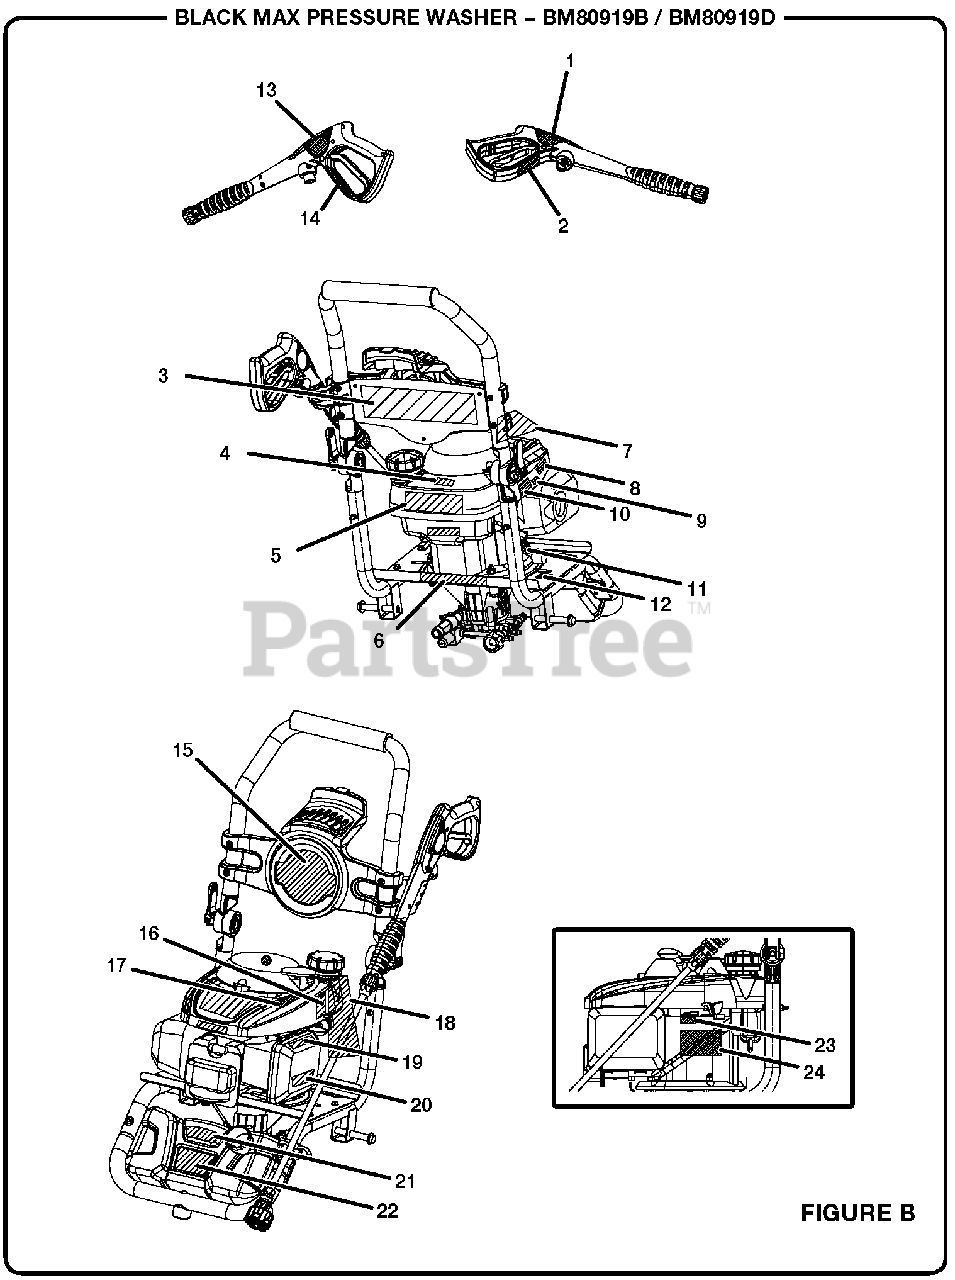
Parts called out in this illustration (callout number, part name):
1	Label (Wand Logo)
2	Label (Warning)
3	Quick Start Label
4	E85 Label
5	Warning Label
6	Data Label (Bm80919b)
7	Nozzle Hang Tag
8	Hot Surface Label
9	Lubricant Label
10	Combustion Warning Label
11	Lubricant Hang Tag
12	Label (Engine Lubricant)
13	Label (Wand Warning)
14	Label (Wand Rating)
15	Label (Performance)
16	Do Not Mix Label
17	Release Water Label
18	Danger Hang Tag
19	Inquiries Label
20	Emc Label
21	Soap Dilution Label
22	Powered By Honda Label
23	Engine On/Off Label
24	Choke Label
